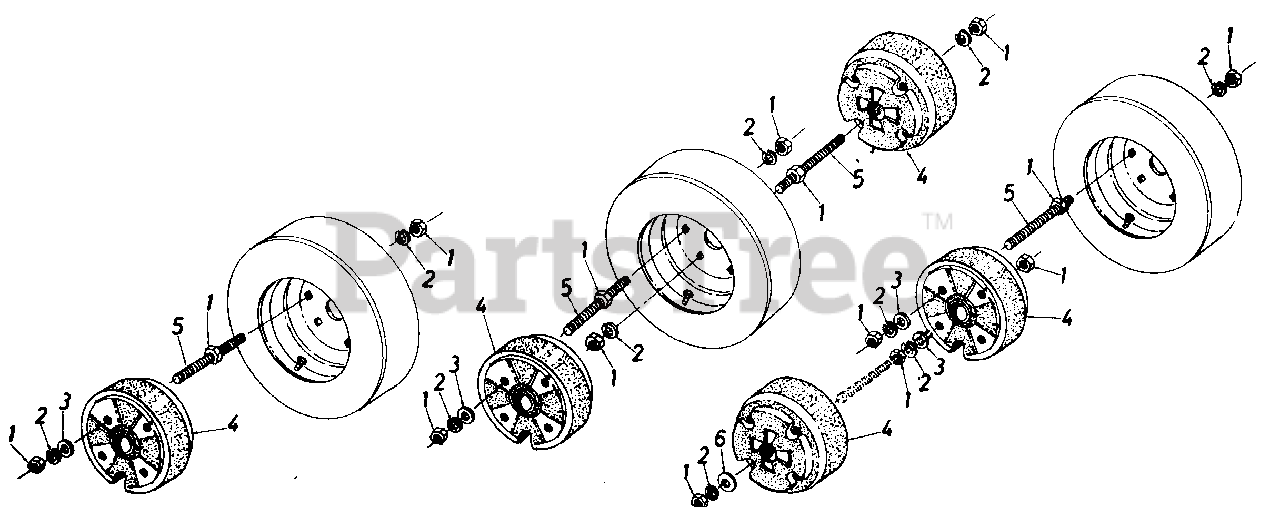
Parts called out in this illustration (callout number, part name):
1	Hex Nut 1/2-13 Thd.
2	Lock Washer 1/2" I.D.
3	FlatWasher. 53" I.D. x.93" O.D.
4	Wheel Weight
5	Rod Threaded 1/2-13 x 9.50 Lg.
6	Fl.-Wash. .50" I.D. x 2.00" O.D.
